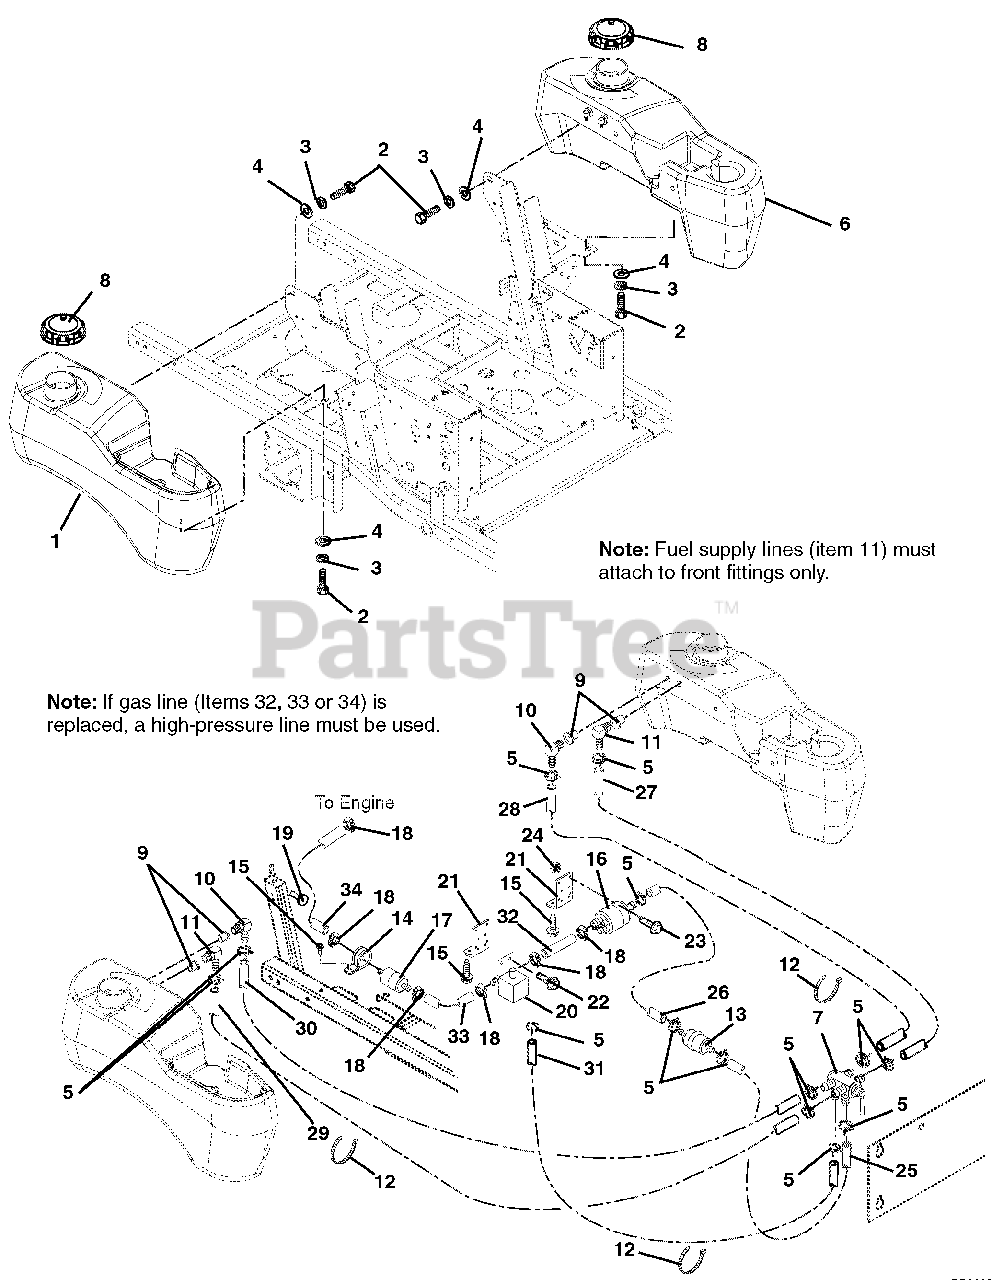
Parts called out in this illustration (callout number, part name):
1	Fuel Tank, Right Hand
2	Bolt, Hex .31-18 x .75 Grade 5
3	Washer, Locking .31 x .078
4	Washer, Flat Steel .38 x .875 x .083
5	Hose, Clamp
6	Fuel Tank Left Hand
7	Valve, Fuel
8	Cap, Gas
10	Fitting, Tank Elbow
11	Fitting, Tank Elbow
12	Tie, Cable
13	Filter, Fuel .31
14	Clamp, 2.18
15	Screw, Tapping .38-16 x .50 Hex Washer Head
16	Pump, EFI Fuel
17	Filter, Fuel
18	Hose Clamp
19	Tube Clip .75
20	Regulator, EFI Fuel
21	Bracket, Pump and Regular Mounting
22	Screw, Tapping .25-20 x .37 Hex Washer Head
23	Screw, Machine 10-24 x .50 Hex Washer Head
24	Nut, Locking Top 10-24
25	Hose, .31 ID Low Pressure
26	Hose, .31 ID Low Pressure
27	Hose, .31 ID Low Pressure Left Hand
28	Hose, .31 ID Low Pressure Left Hand
29	Hose, .31 ID Low Pressure Right Hand
30	Hose, .31 ID Low Pressure Right Hand
31	Hose, .31 ID Low Pressure
32	Gas Line .31 ID High Pressure
33	Gas Line .31 ID High Pressure
34	Gas Line .31 ID High Pressure
